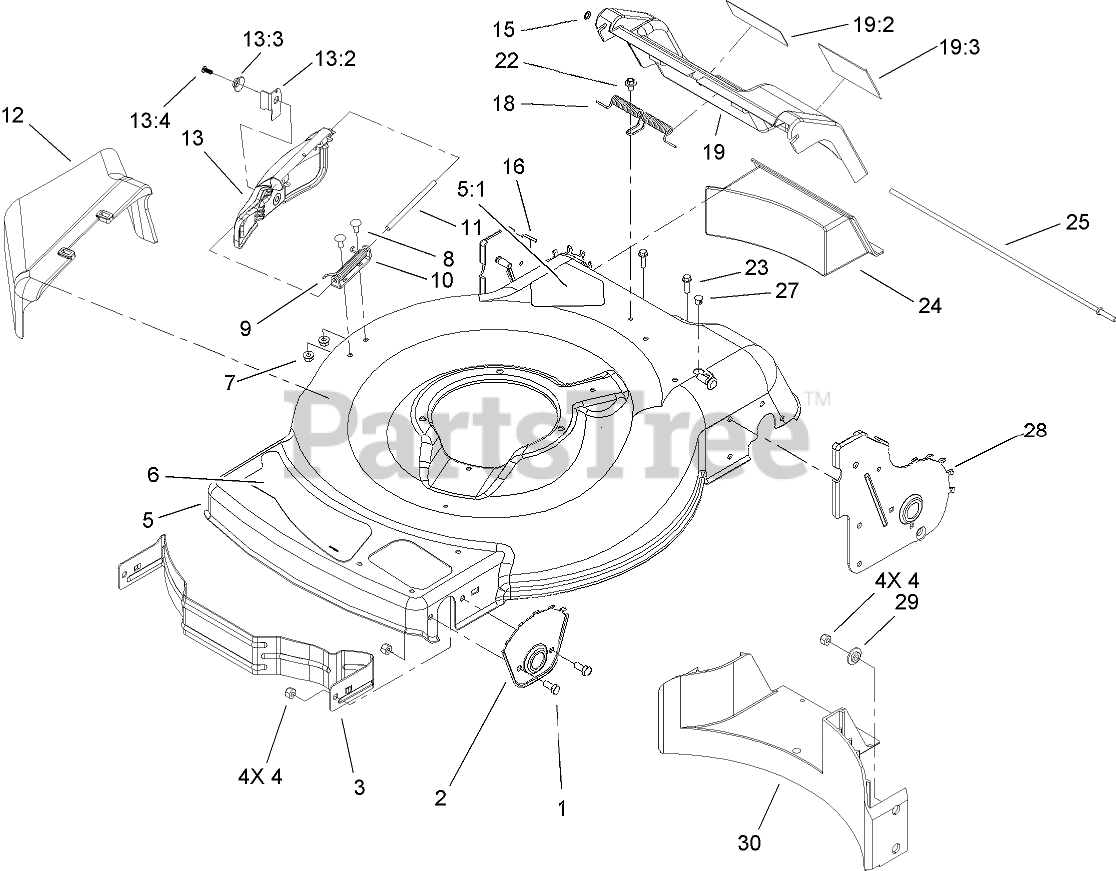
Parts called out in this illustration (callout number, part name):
1	SCREW-HH
2	Plate-HOC, Front
3	Baffle-Front
4	NUT-LOCK, NI
5	HOUSING
5:1	DECAL-DANGER
6	Decal-Deck
7	NUT-HHF
8	SCREW-CARR
9	SPRING-TORSION
10	BRACKET-COVER
11	ROD-COVER
12	CHUTE-DISCHARGE, SIDE
13	DISCHARGE DOOR ASM
13:2	LATCH-DOOR
13:3	CAP-DOOR
13:4	SCREW-PLASTITE
15	NUT-PUSH
16	11 INCH RH HOC PLATE ASM
18	Spring-Door, Rear
19	REAR DOOR ASM
19:2	DECAL-WARNING
19:3	DECAL-WARNING
22	SCREW AND WASHER ASM
23	SCREW-HWH
24	Plug-Discharge, Rear
25	Rod-Pivot, Rear Door
27	Plug-Dome
28	11 INCH LH HOC PLATE ASM
29	Washer-Stepped
30	Baffle-Rear
